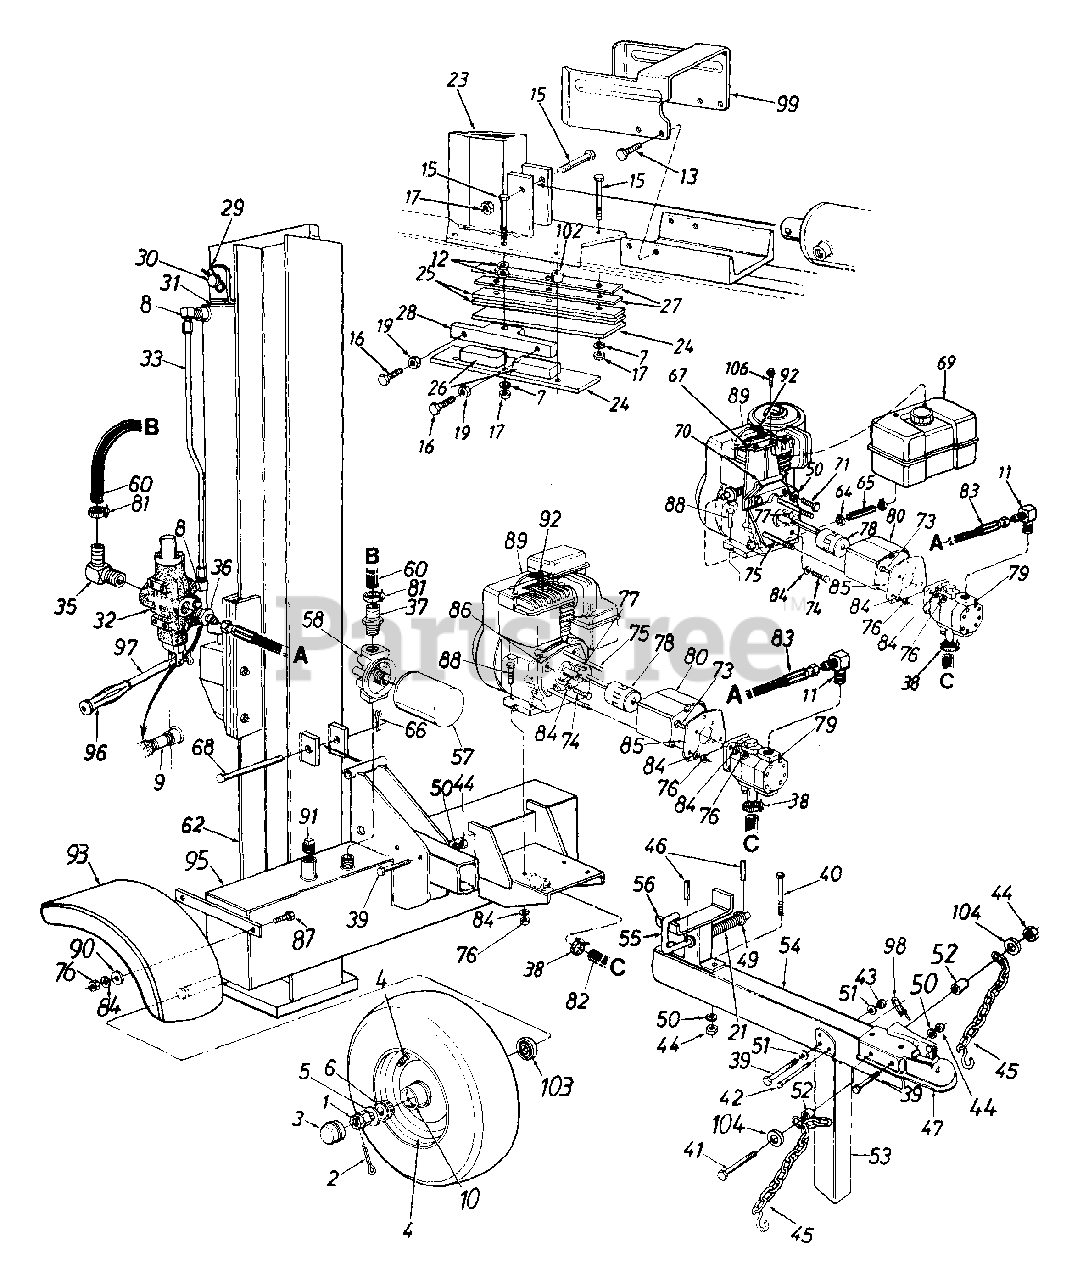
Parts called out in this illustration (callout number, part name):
1	Slotted Nut 3/4-16 Thd.
2	Cotter pin 5/32" Dia.
3	Hub Cap
5	Fl-Wash. .76" I.D. x 1.5" O.D.
6	Bearing Cone
7	L-Wash. 1/2" I.D.
8	90ø Solid Male Adaptor
9	Pipe Nipple 1/2 NPT
10	Bearing Cup
11	90ø Male Adapter
12	Fl-Wash. .531" I.D. x .94" O.D.
13	Hex Cap Scr. 3/8-16 x 1" Lg.
15	Hex Bolt 1/2-20 x 2.75" Lg. (Grade 8)
16	Hex Bolt 3/8-24 x 1.5" Lg.
17	Hex L-Nut 1/2-20 Thd.
19	Hex Jam Nut 3/8-24 Thd. (Grade 5)
21	Comp. Spring 4" Lg.
29	External Cotter Pin
30	Cylinder Mounting Pin
33	Metal Pressure Tube
35	Return Elbow
36	Adapter
37	3/4" Hose Barb.
38	Hose Clamp
39	Hex Bolt 3/8-16 x 3" Lg. (Grade 8)
40	Hex Bolt 3/8-16 x 4" Lg.
41	Hex Bolt 3/8-16 x 4.25" Lg. (Grade 5)
42	Clevis Pin 5/16 x 2.5" Lg.
43	Hex L-Nut 3/8-16 Thd.
44	Hex Nut 3/8-16 Thd.
45	Chain - Tow Hitch
46	Roll Pin
47	Hitch Coupler
49	Fl-Wash. .635" I.D. x .93" O.D.
50	L-Wash. 3/8" I.D.
51	Fl-Wash. .406" I.D. x .75" O.D.
52	Spacer .44" Lg.
55	Locking Rod
57	Fllter Element
58	Fllter Head
60	Return Hose 3/4" I.D. x 44" Lg.
65	Fuel Line 15" Lg.
66	Cotter Pin 1/8" Dia.
67	Tank Mtg. Brkt.
68	Hinge Pin 1/2 x 4.8" Lg.
69	Fuel Tank Ass'y.
70	Support Brkt.
71	Hex Bolt 3/8-16 x 1" Lg.
73	Hex Bolt 5/16-24 x 1" Lg.
74	Hex Bolt 5/16-24 x .62" Lg.
75	Hex Bolt 5/16-24 x 4" Lg.
76	Hex Nut 5/16-24 Thd.
77	Sq. Key 3/16" x .75"
78	Flexible Coupling
79	Gear Pump
80	Coupling Shield
81	Hose Clamp 5/8"
82	Suction Hose
83	High Pressure Hydraulic Hose 48"
84	L-Wash. 5/16" I.D.
87	Hex Bolt 5/16-24 x .75" Lg.
88	Hex Bolt 5/16-24 x 1.75" Lg.
89	Engine
90	Fl-Wash. .344" I.D. x .875" O.D.
91	L-Vent Pipe Plug
92	Spark Plug Boot
97	Control Handle
98	Spring Pin
102	Spacer 1/2" I.D. x .86" Lg.
103	Bearing Seal Only
104	Fl-Wash. 3/8" I.D. x .87" O.D.
106	Hex AB-Tap Scr. 1/4 x .75" Lg.
